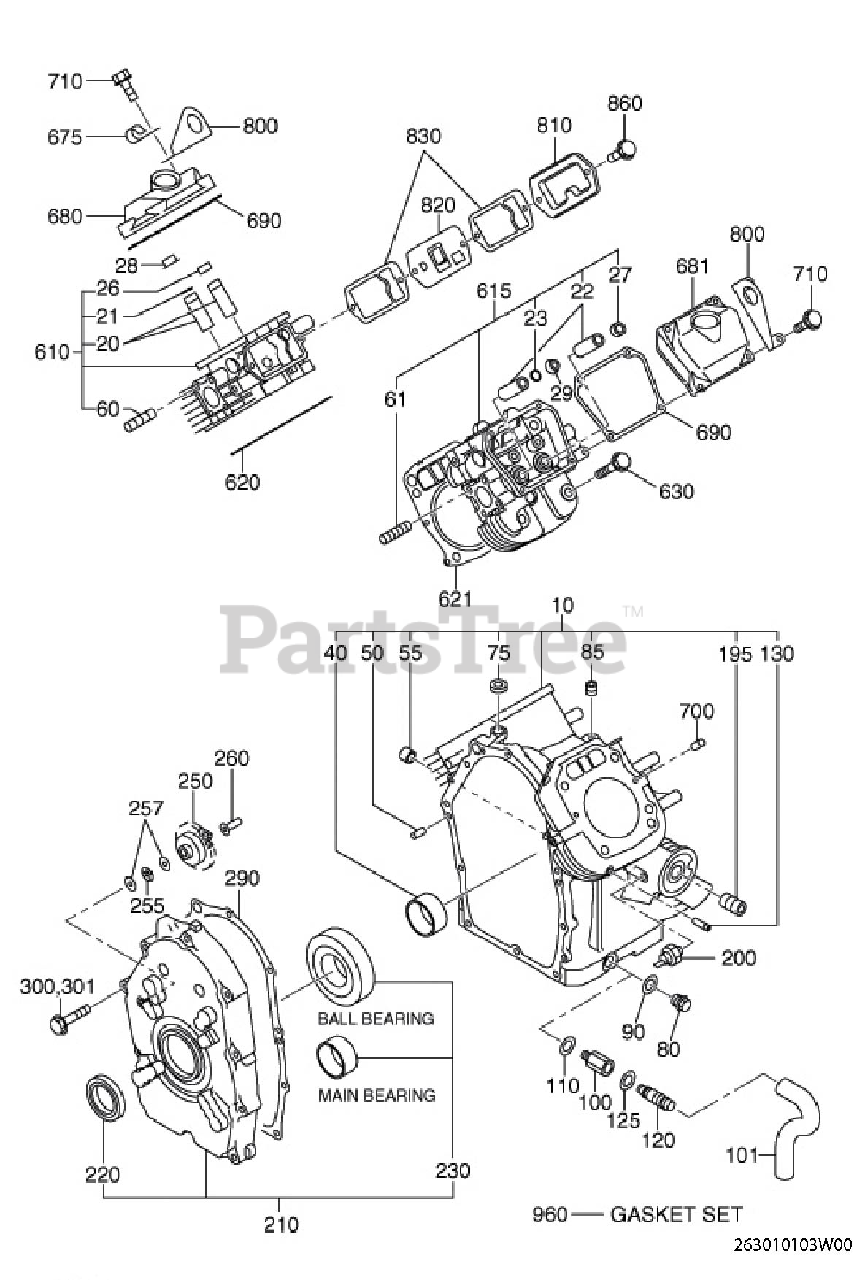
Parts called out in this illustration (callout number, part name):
20	VALVE GUIDE
21	CLIP
22	VALVE GUIDE
23	CLIP
26	SEAL-EXH VALVE
27	SEAL-EXH VALVE
28	RETAINER PLATE
29	RETAINER PLATE
40	MAIN BEARING
55	PIPE
60	STUD
61	STUD
75	OIL SEAL
80	OIL DRAIN PLUG
85	BLIND PLUG
130	PIPE(PULSE)
195	UNION
200	SWITCH OIL PRESSURE
210	MAINBEARING COVER CP
220	OIL SEAL
230	MAIN BEARING
250	GOVERNOR GEAR CP
255	THRUST BEARING
260	GOVERNOR SLEEVE
290	GASKET (M.B COVER)
300	FLANGE BOLT
610	CYLINDER HEAD 1 CP
615	CYLINDER HEAD 2 CP
620	GASKET 1 (CYL HEAD)
621	GASKET 2 (CYL HEAD)
630	FLANGE BOLT
690	GASKET(ROCKER COVER)
700	DOWEL PIN
710	FLANGE BOLT
810	BREATHER COVER
820	BREATHER PLATE CP
830	GASKET(BREATHERPLATE
860	FLANGE BOLT
